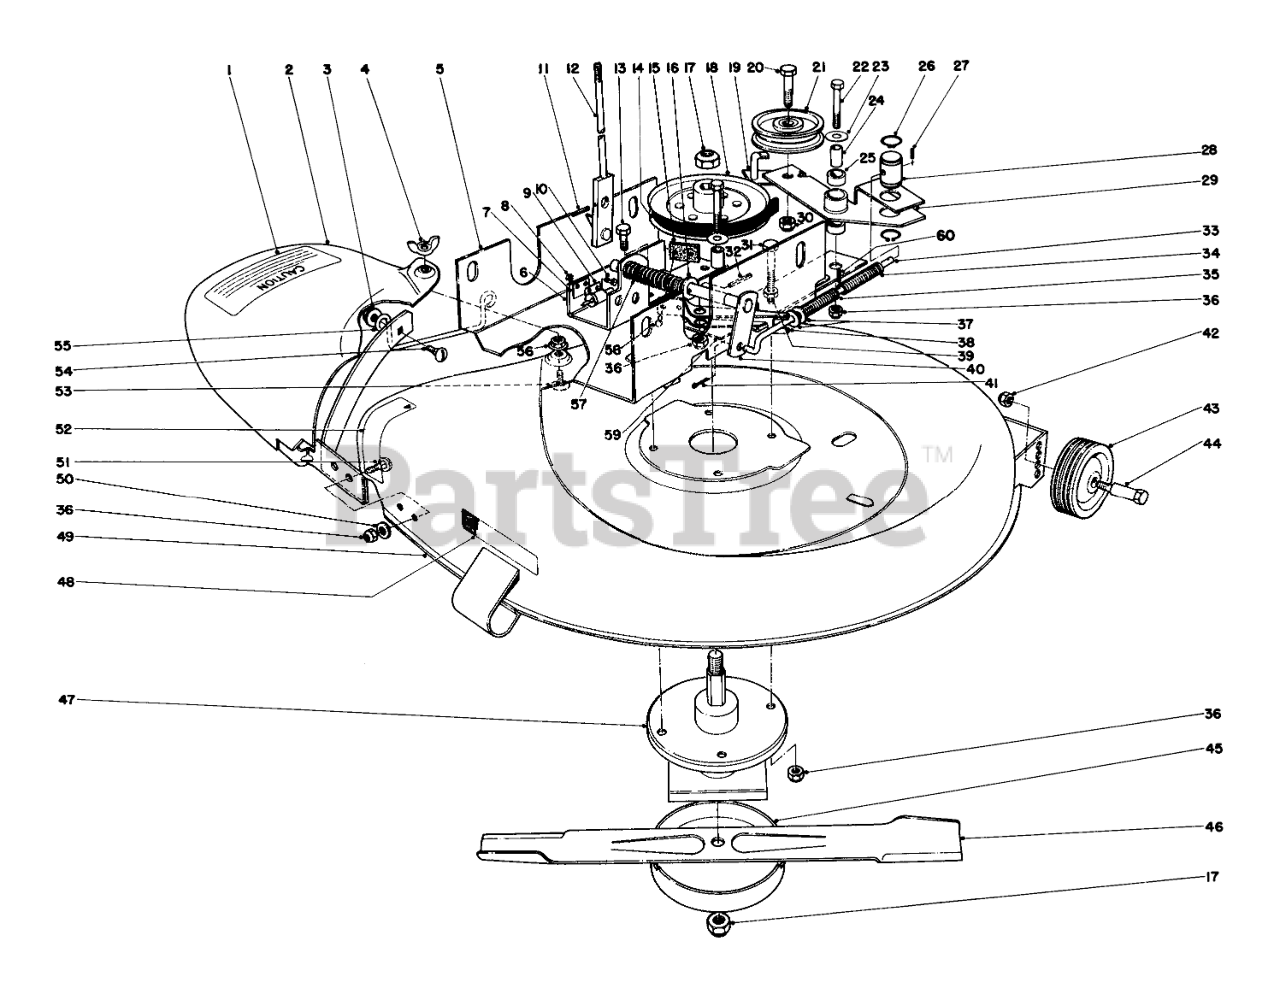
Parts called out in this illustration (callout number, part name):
1	Decal
2	DEFLECTOR WA R
3	NUT-LOCK, HHF
4	Wing Nut
5	CHANNEL HT ADJ R
6	Mounting Bracket Blade
7	Spacer Switch
8	NUT-KEPS
9	Switch-Interlock
11	PIN-SPIRAL
12	Lever Deck Engagement
13	Screw
14	V-BELT
15	BLADE BRAKE LINING
16	WASHER-FLAT
18	DECK PULLEY R
19	Belt Retainer
20	SCREW-HH
21	Flat Idler
22	SCREW-HH
23	WASHER-PLAIN
24	PIVOT SPACER
25	Bushing
26	RING-RETAINING
27	PIN-ROLL
28	Pin-Pivot
29	Idler Arm (Incl. Ref. #25)
30	NUT-LOCK, CONE
31	SCREW-HH
32	PIN-SPRING
33	BLADE ENGAGE ROD
34	Spring Deck Idler
35	Spring Deck Brake
36	NUT-LOCK, CONE
37	WASHER
38	Blade Brake (Incl. Ref. 15 & 58)
39	NUT-JAM
40	Linkage
41	PIN-COTTER
42	Nut
43	Wheel
45	Cup
46	Blade
47	Mower Spindle
48	Decal-Deck Inst.
49	HOUSING WA R
50	WASHER-FLAT
51	BOLT-CARR
52	Decal Housing
53	Carriage Bolt
54	SCREW-CARRIAGE
55	Bracket Foot Guard
56	PAL NUT
57	COMP SPRING O
58	Rivet
59	Bracket Idler Mounting
60	PIN-SPRING
